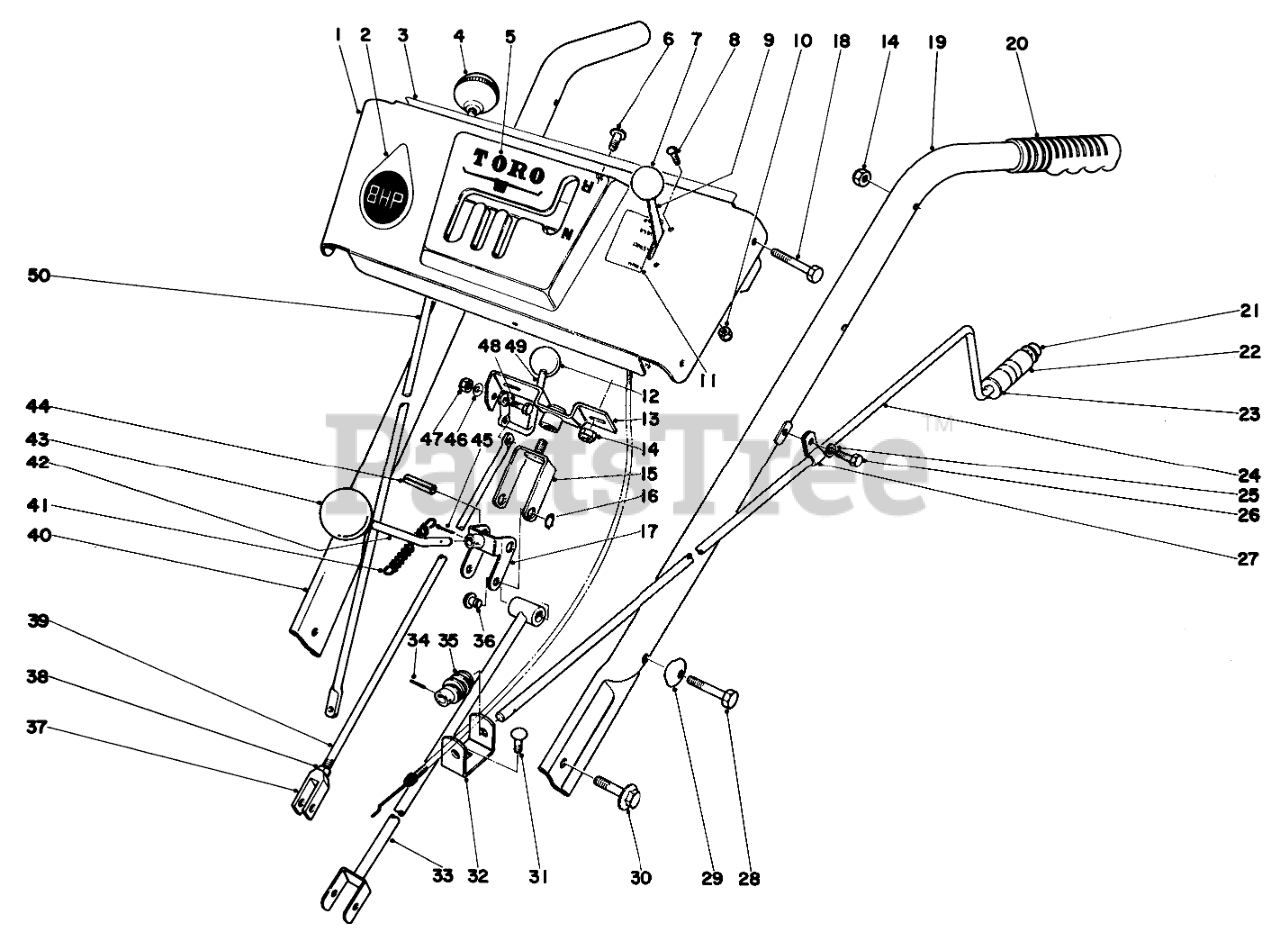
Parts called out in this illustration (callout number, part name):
1	Escutcheon Plate (Incl. Ref. Nos. 3, 5 & 11)
2	Decal, Model 31727
3	Decal, Escutcheon Back
4	KNOB-LEVER
5	Decal, Escutcheon
6	Screw, Machine
7	KNOB-CONTROL
8	SCREW-PPH
9	Throttle Contrl
10	Nut
11	Decal, Throttle
12	Knob
13	SWIVEL BLOCK WA
14	NUT-LOCK
15	Pivot Bracket
16	Ring-Snap
17	Control Bracket
18	SCREW-HH
19	Left Handle
20	Grip Handle
21	Speed Nut
22	Chute Control Grip
23	WASHER-FLAT
24	ROD CHUTE CONTROL
25	WASHER-LOCK
26	SCREW-HH
27	R-CLAMP
28	SCREW-HH
29	Curved Washer
30	SCREW-HHF
31	SCREW-CARR
32	Bracket Worm
33	Trunnion
34	PIN-SPRING
35	GEAR-WORM, CHUTE
36	Pin Shift Lever
37	Yoke
38	NUT-HJ
39	Drag Link
40	Handle, R.H.
41	CONT ROD SPRING 0
42	Shift Rod
44	PIN-ROLL
45	PIN-COTTER
46	Lynch Pin
47	NUT-LOCK
48	SCREW-HH
49	Handle, Auger Shaft
50	Rod Wheel Clutch
